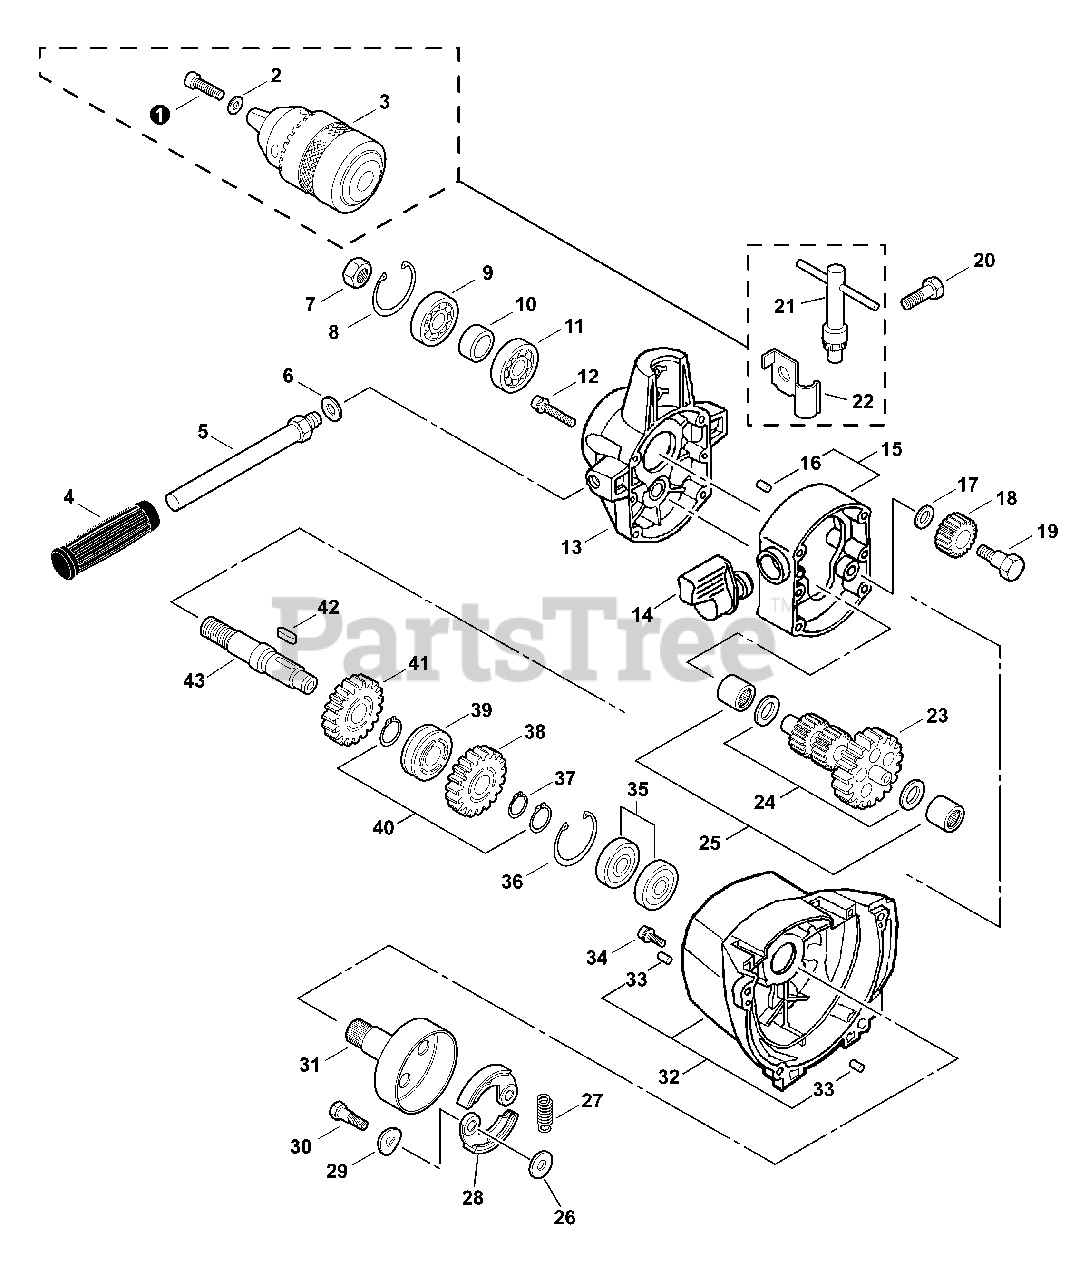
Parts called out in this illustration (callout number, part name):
1	SCREW - 6×20
2	WASHER - 6
3	CHUCK - KEYED
4	GRIP, HANDLE
5	HANDLE - LEFT
6	WASHER - 10
7	NUT - 12
8	RING, RETAINING - 32
9	BEARING, BALL - 6002
11	BEARING, BALL - 6002
12	SCREW - 5×55
13	CASE, GEAR
14	LEVER, CLUTCH
15	GEAR CASE ASY
16	PIN, LOCATING
18	GEAR, SPUR
19	BOLT, SHAFT
20	BOLT - 10×15
21	KEY, CHUCK
22	CLAMP, CHUCK KEY
23	GEAR ASY
25	BEARING, NEEDLE
26	WASHER - 6
27	SPRING, CLUTCH
28	SHOE, CLUTCH
29	WASHER - SPRING
30	BOLT, SHAFT
31	DRUM, CLUTCH
32	FAN CASE ASY
33	PIN, LOCATING
34	SCREW - 5×18
35	BEARING, BALL - 6002D
36	RING, RETAINING - 32
37	RING, RETAINING - 12
38	GEAR, SPUR
39	CAM, CLUTCH ADJUSTER
40	RING, RETAINING - 15
41	GEAR, SPUR
42	KEY - 4×16
43	SHAFT, GEAR
